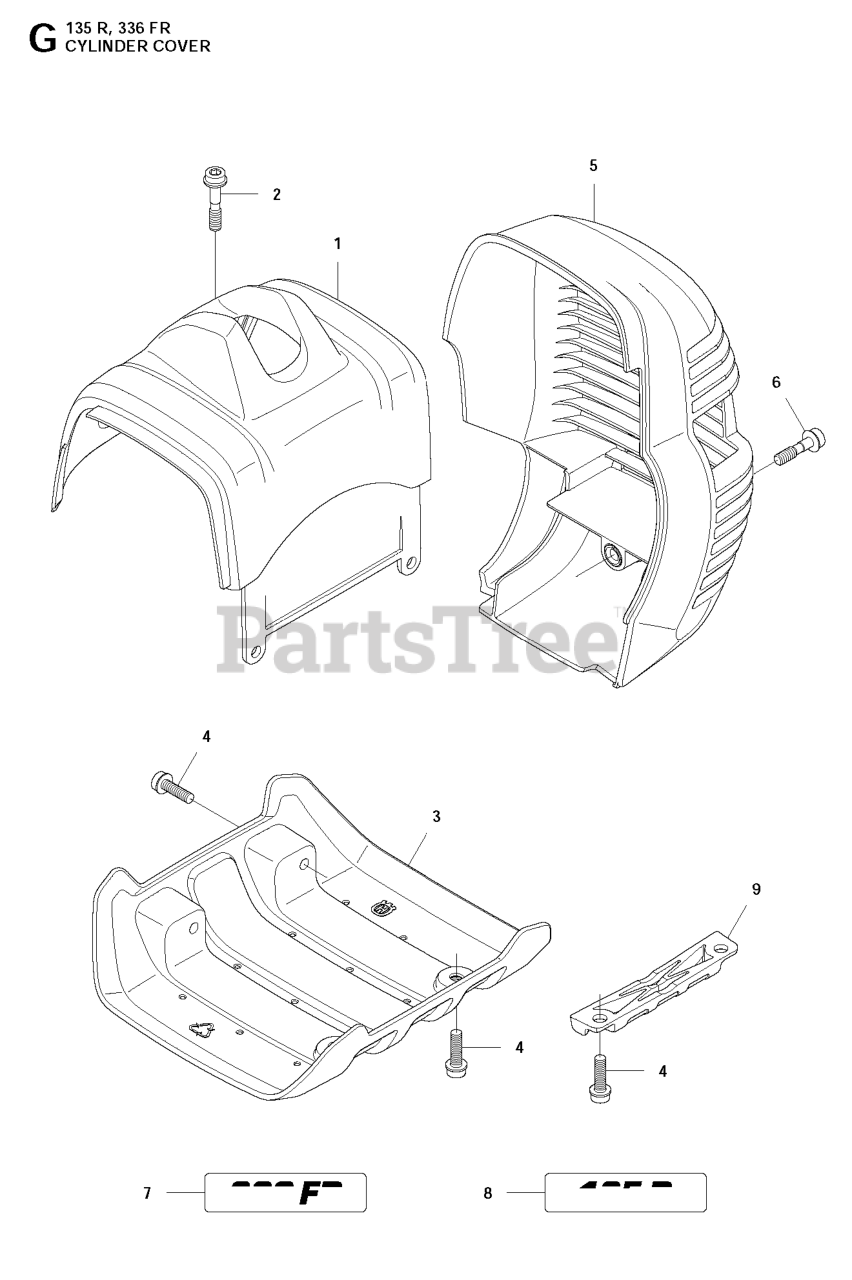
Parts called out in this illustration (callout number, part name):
1	CYLINDER COVER
2	SCREW IHSCFMO
3	PROTECTIVE PLATE
4	SCREW IHSCFM
5	MUFFLER GUARD
6	SCREW IHSCFMO
7	LABEL
8	LABEL
9	DAMPER
